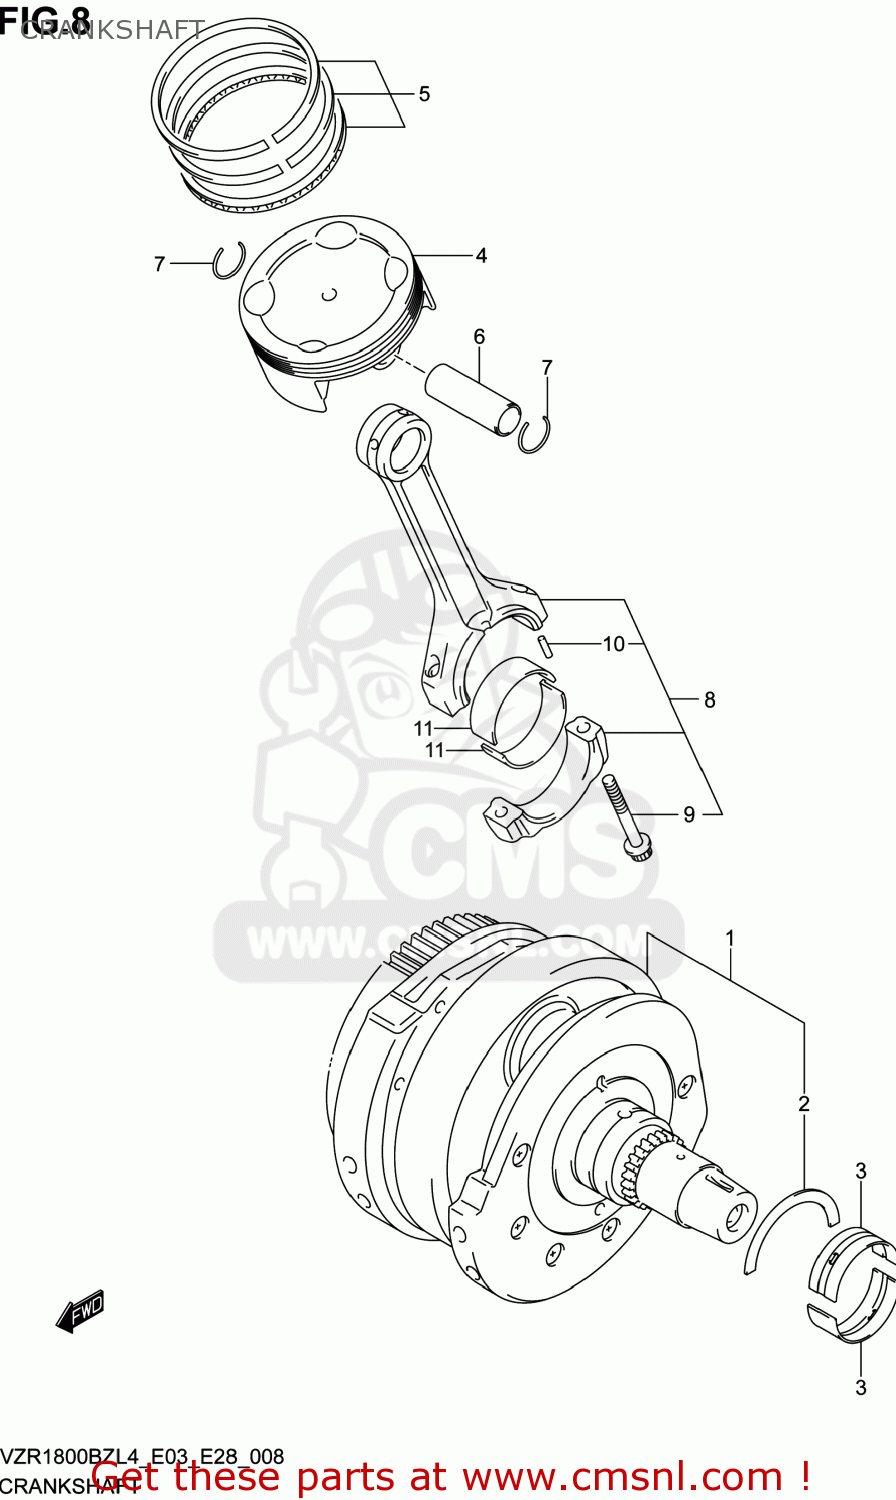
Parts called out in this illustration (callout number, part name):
1	CRANKSHAFT SET
2	WASHER,CRANK THRUST
3	BEARING,CRANKSHAFT
4	PISTON
5	RING SET,PISTON
6	PIN,PISTON
7	CIRCLIP
8	CONNECTING ROD ASSY
9	BOLT,CONNECTING ROD
10	PIN
11	BEARING,CRANK PIN
